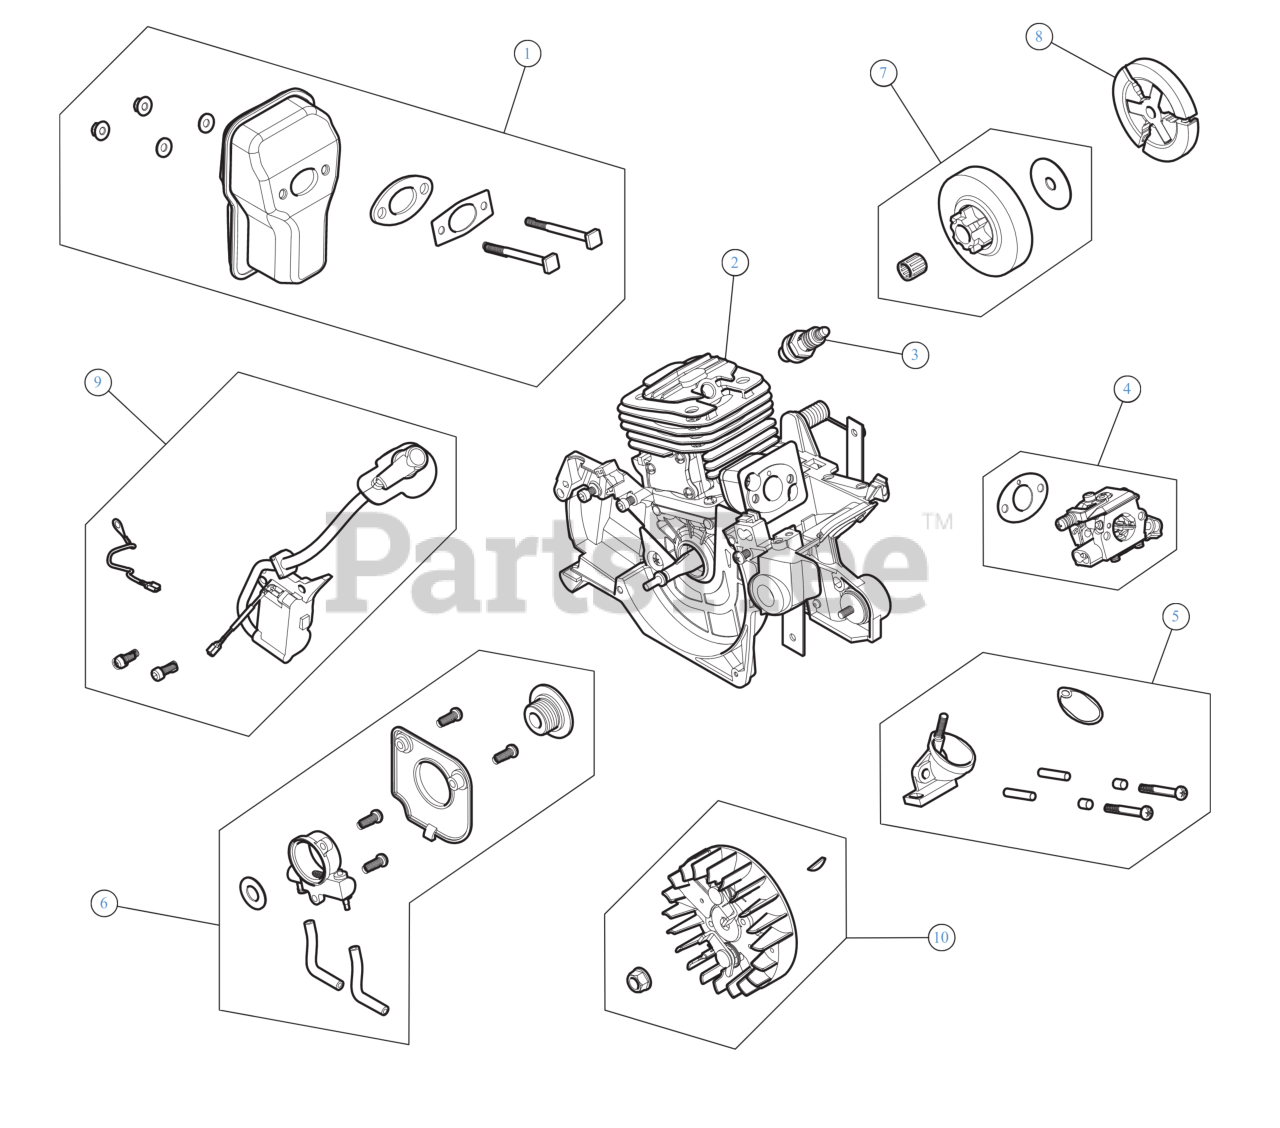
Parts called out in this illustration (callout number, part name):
1	MUFFLER
2	42CC SHORT BLOCK
3	SPARK PLUG
4	CARBURETOR
5	CARBURETOR HARDWARE
6	OIL PUMP
7	CLUTCH DRUM
8	CLUTCH
9	IGNITION MODULE
10	FLYWHEEL
